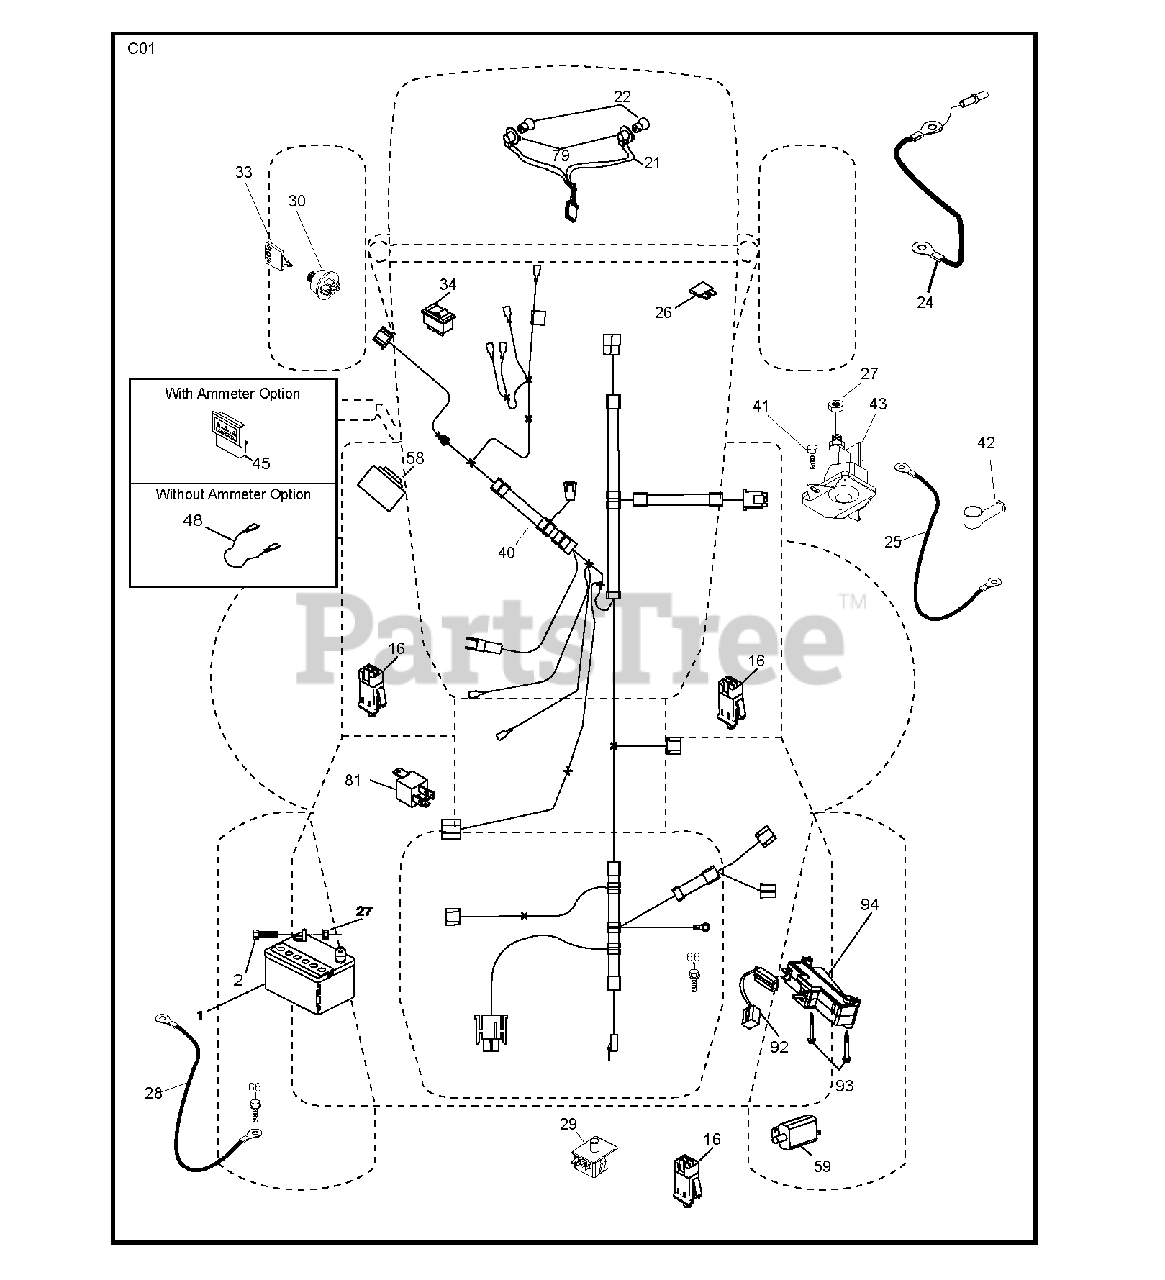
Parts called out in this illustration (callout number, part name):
1	REPL BY 532 12 38-99
16	SWITCH INTERLOOK PUSH-IN
21	HARNESS ASSY LIGHT
22	LIGHTBULB
24	BATTERY CABLE GT
25	CABLE BATTERY
26	FUSE 20AMP
27	NUT
28	CABLE GROUND
29	SWITCH.SEAT.DP W/RAMPS
30	SWITCH.IGN.DELTA.W.LGH.ROS
33	KEY.CHAIN.BLISTER.PACK.GEN.INT
34	SWITCH LT
42	TERMINAL COVER
43	SOLENOID.W/BRASS.PLUNG
58	BUZZER
66	SCREW LT
79	BULB HOLDER ASM.
81	RELAY.ASSY.T
92	HARNESS.PIGTAIL.CONSLE
93	SCREW.PLASTITE
94	MODULE.REVERSE.ROS
